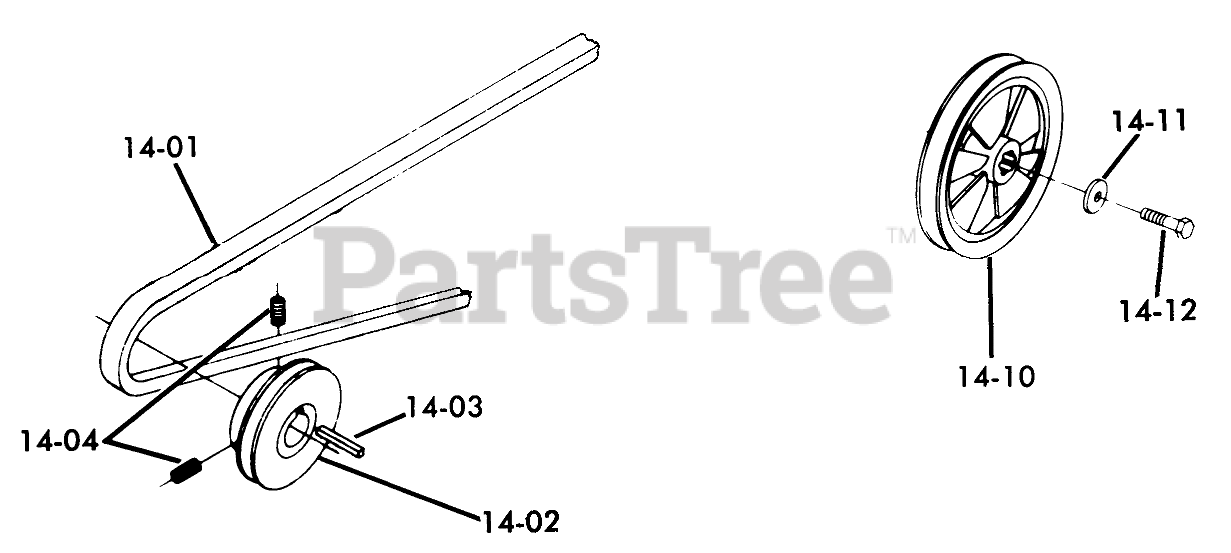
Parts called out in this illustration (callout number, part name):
14-01	V BELT
14-02	PULLEY
14-04	Set Screw
14-10	PULLEY
14-11	WASHER
14-12	Bolt
